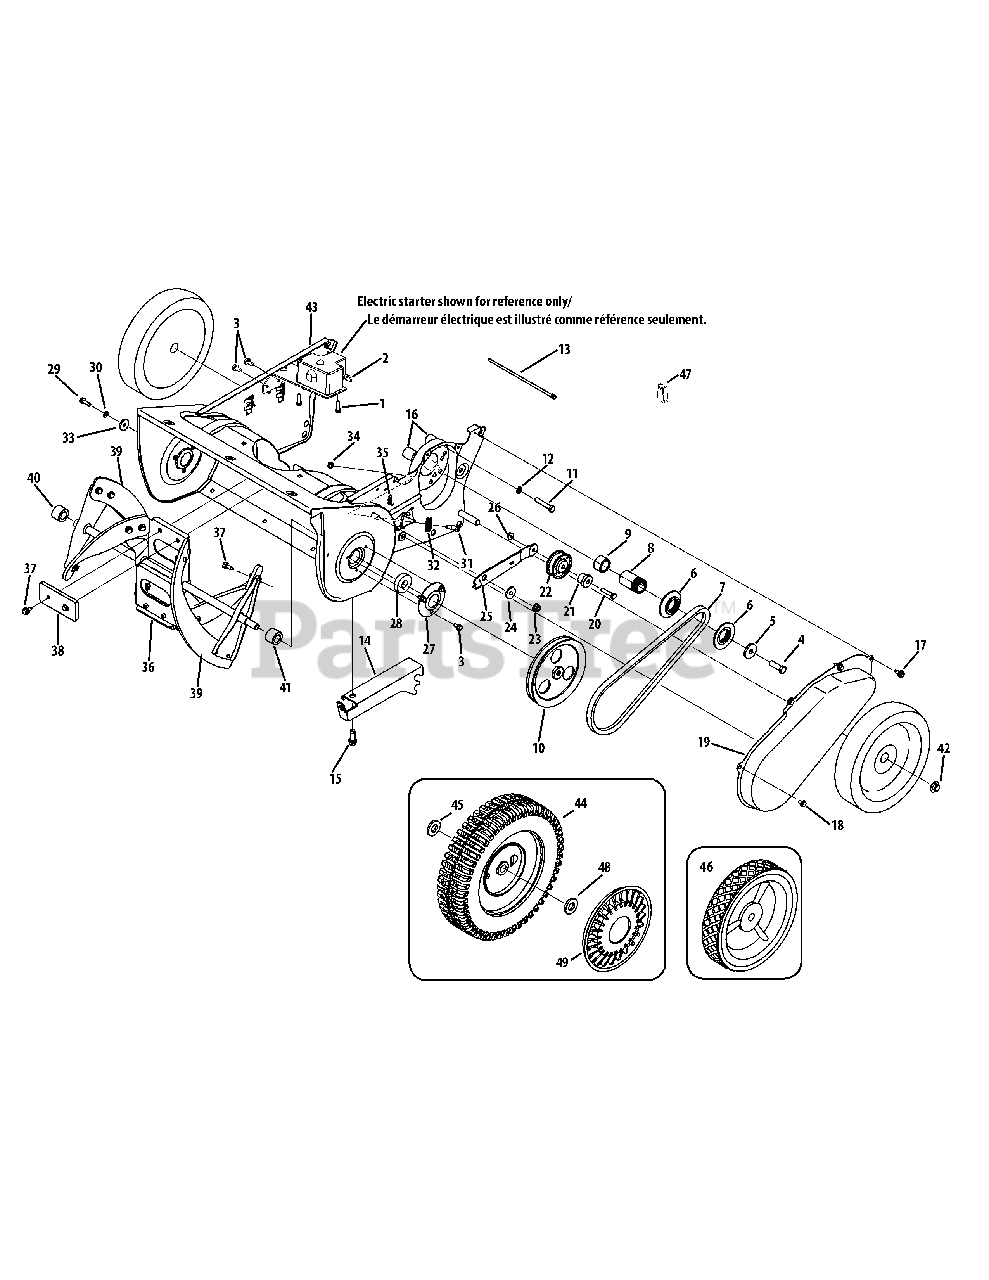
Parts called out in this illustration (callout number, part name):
1	Hi-Lo Screw #12-16 x .75
2	Electric Start Support Bracket
3	Hex Tap Scr. 1/4-14 x .5" Lg.
4	Hex Hd. Cap Screw 3/8-24 x 1.75
5	Flat Washer .406 x 1.25 x .157
6	Pulley Half 4L-V x 2.30 OD
8	Spacer .875 ID x 1.185 OD
9	Spacer .88 ID x 1.18 OD x .74" Lg.
10	V-Pulley 1/2 x 6,0" OD
11	Hex Bolt 5/16-24 x 1.75
12	Lockwasher 5/16
13	Push Mount Tie
14	Engine Support Bracket
15	Hex Wash HD Tap Scr 3/8-16 x .88
16	Spacer .875 x .320 x 1.10
17	Hex B-Tap Scr 1/4-28 x .25" Lg
18	Hex Wash HD Tapp Scr 1/4-20 x .375
20	Hex Screw 1/4-20 x 1.25 Gr. 5
21	Shoulder Spacer
22	Idler Pulley (1/4" hole)
23	Flange Locknut 5/16-18 Gr. F, Nylon
24	Shoulder Spacer .25 Thk.
26	Flange Locknut 1/4-20 Gr. F, Nylon
28	Ball Bearing .625 x 37 x 12.63
29	Thd Form ing Scr. 1/4-20 x .75 Lg.
30	L-Wash 1/4 ID
31	Hex Shld.Scr.1/4-28 x .375
32	Cable Guide Roller
33	Flat Washer .25 ID x .93 OD x .125
34	Hex Ins Jam L-Nut 1/4-28
35	Extension Spring .33 OD x 1.12 Lg.
37	Hex B-Tap Scr 1/4-28 x .25" Lg
38	Rubber Paddle
39	Rubber Spiral-Crescent
40	Auger Spacer RH
41	Auger Spacer LH
42	Push Cap x 1/2" Rod
44	Wheel, 9 x 2.125 dia. Lug
45	Flat Washer .510 ID x 1.0 OD x .125
46	Wheel, 7.0 x 1.61
47	Alternator Cap (optional)
48	Flat Washer .53 ID x .93 OD x .050
